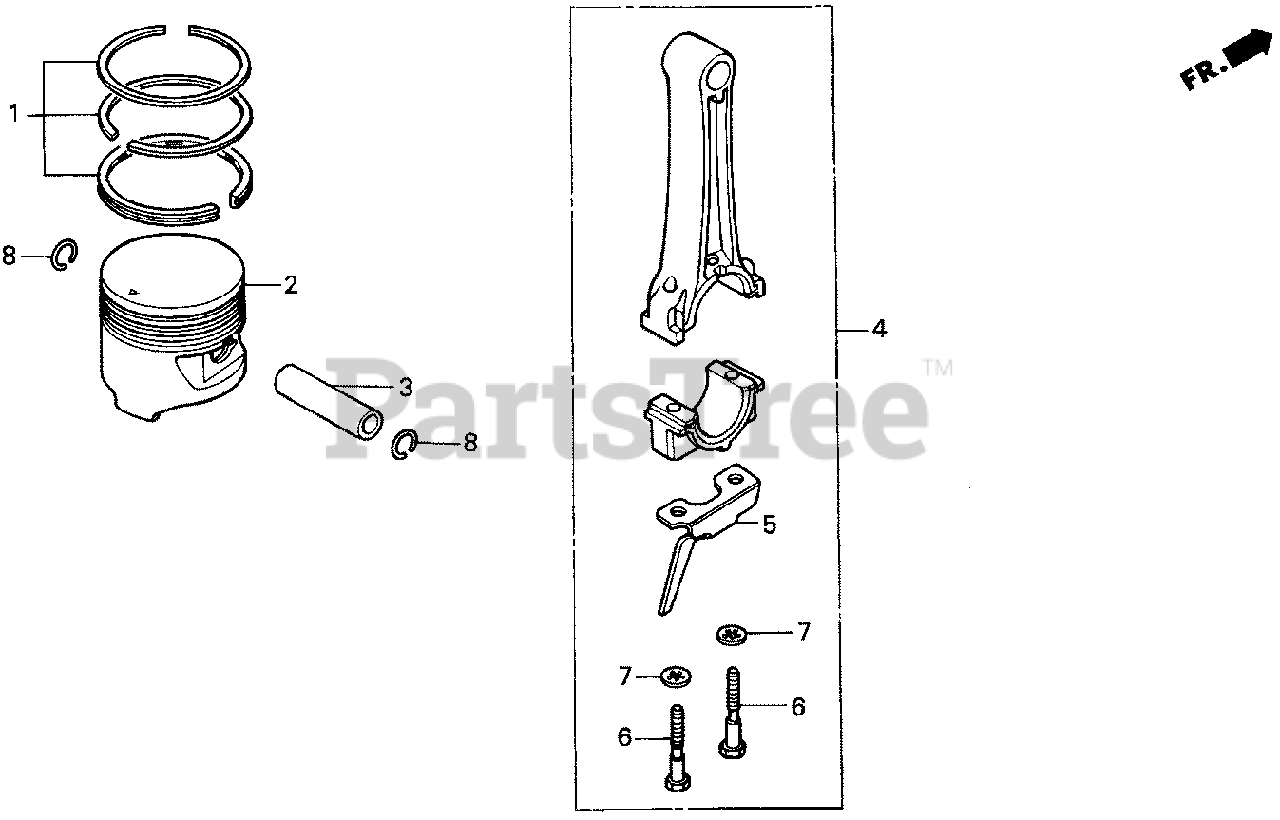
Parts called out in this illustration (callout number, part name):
1	RING SET, PISTON
1	RING SET, PISTON (OS 0.25)
1	RING SET, PISTON (OS 0.50)
1	RING SET, PISTON (0.75)
2	PISTON (STD)
2	PISTON (OS 0.25)
2	PISTON (OS 0.50)
2	PISTON (0.75)
3	PIN, PISTON
4	ROD ASSY., CONNECTING
4	ROD ASSY., CONNECTING (US)
5	DIPPER, CONNECTING ROD
6	BOLT, CONNECTING ROD (7MM)
7	WASHER, LOCK (7MM)
8	CLIP, PISTON PIN (16MM)
